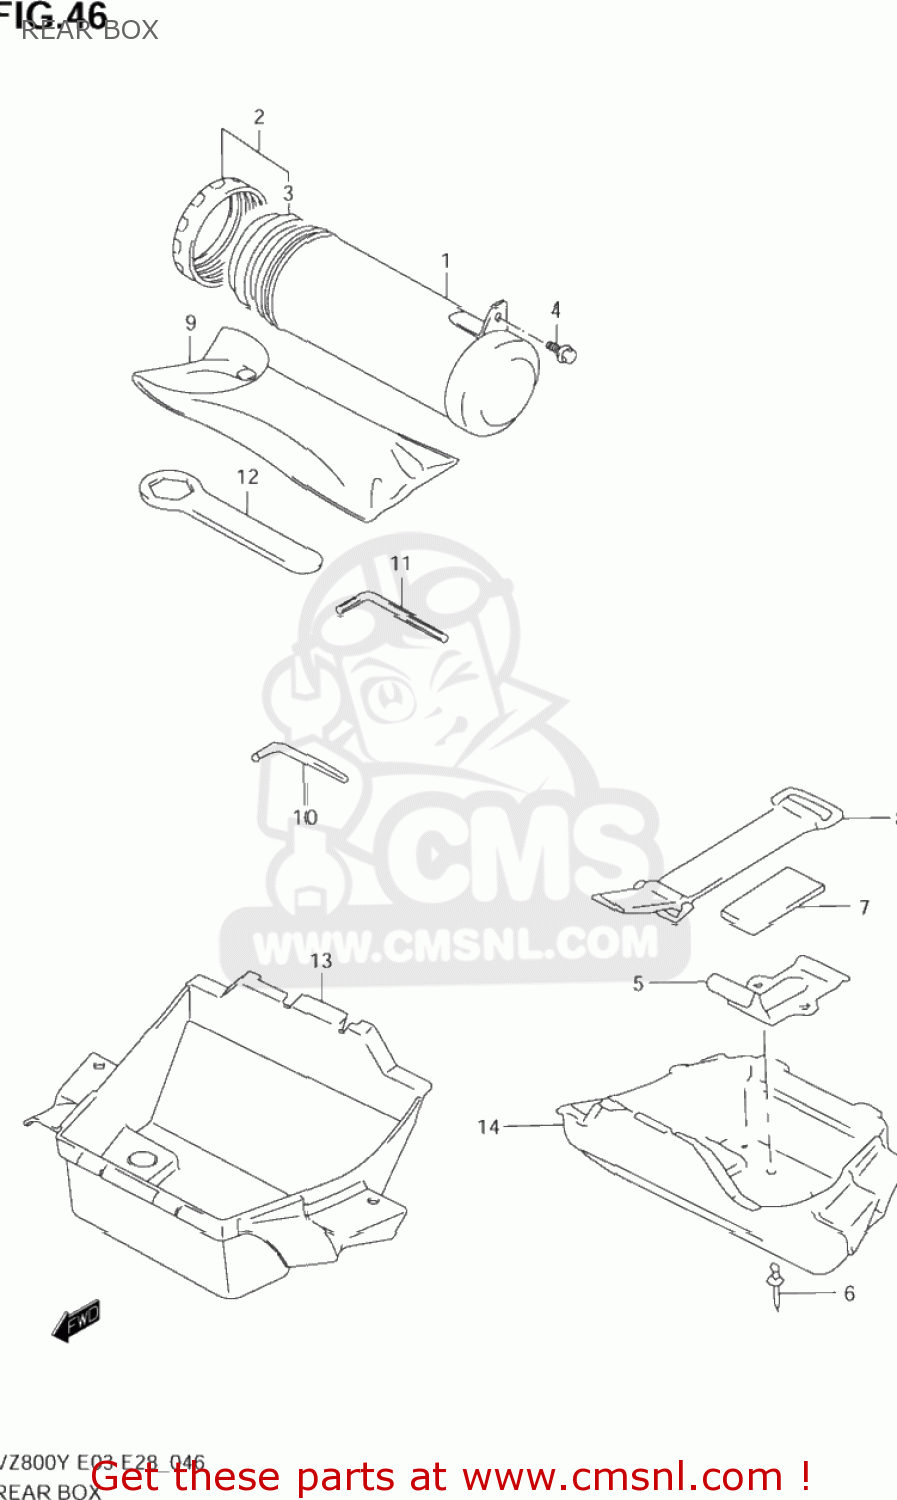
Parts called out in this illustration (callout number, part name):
1	HOLDER,TOOL
2	CAP SET,TOOL HOLDER
3	CUSHION,TOOL HOLDER
4	BOLT
5	HOLDER,TOOL
6	RIVET
7	PROTECTOR(170X95X3.0)
8	BAND,TOOL
9	TOOL ASSY
10	SPANNER,HEXAGON(4)
11	SPANNER,HEXAGON(6)
12	RING SPANNER(22)
13	BODY,LUGGAGE BOX
14	BODY,LUGGAGE BOX
